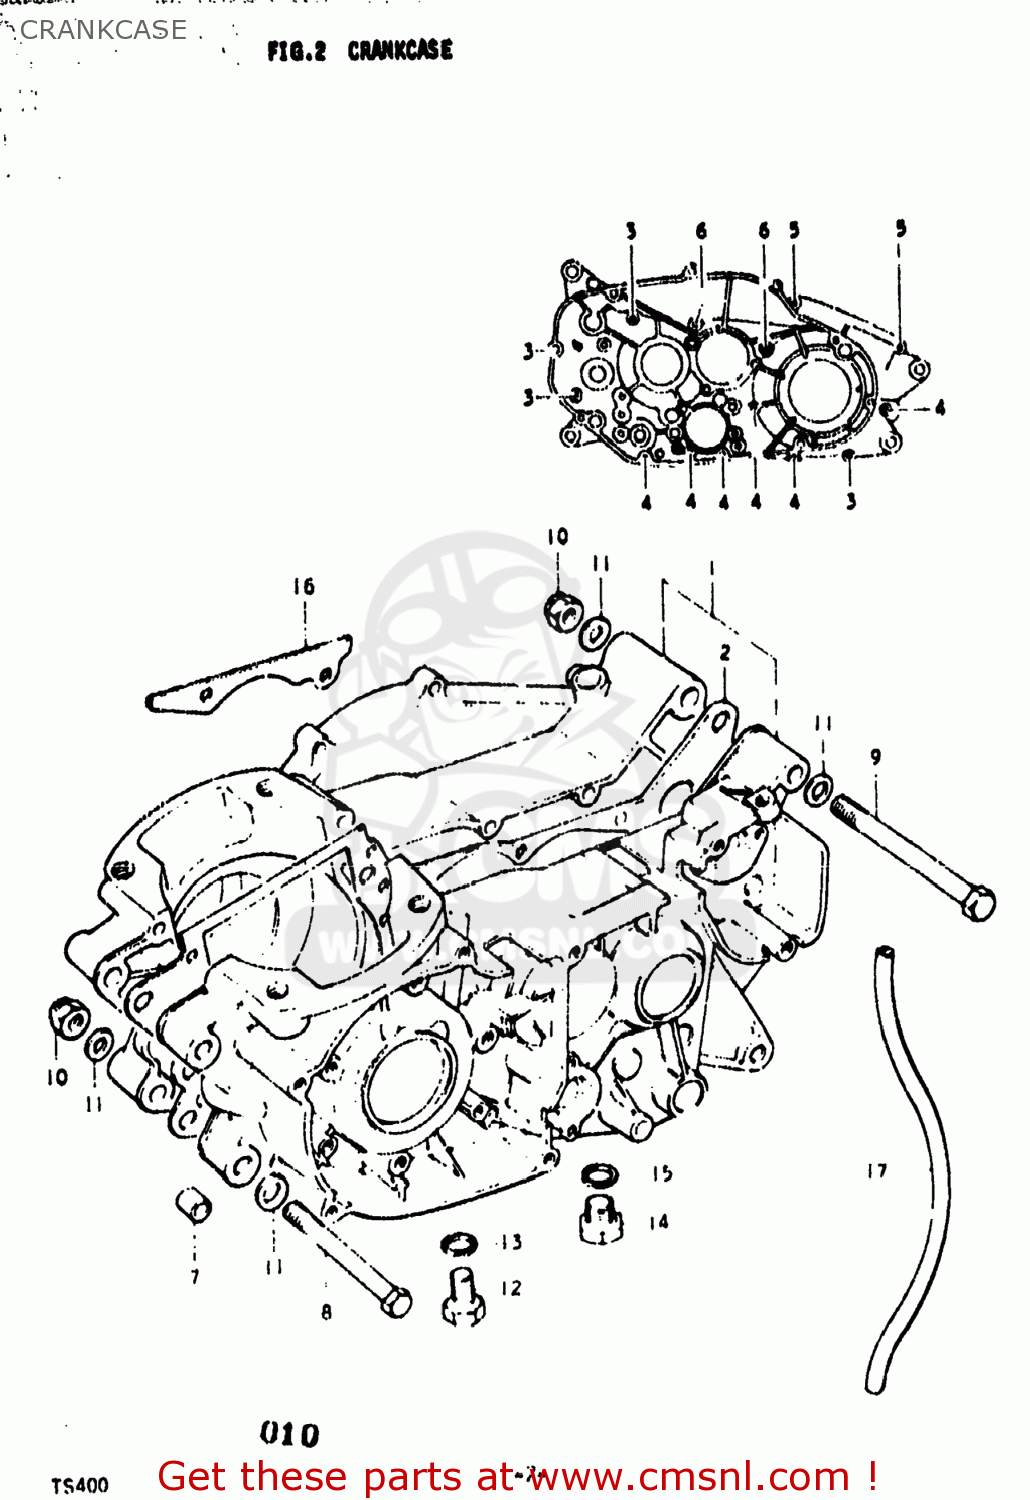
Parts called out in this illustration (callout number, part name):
1	CRANKCASE SET
2	GASKET,CRANKCASE (NAS)
3	SCREW
4	SCREW 6X60
5	SCREW 6X70
6	SCREW 6X80
7	PIN
8	BOLT
9	BOLT
10	NUT
11	WASHER
12	PLUG
13	GASKET(10X14X3.6) (NAS)
14	PLUG
15	GASKET(14X19.2X2) (NAS)
16	PLATE,OIL RESERVOIR
17	HOSE
